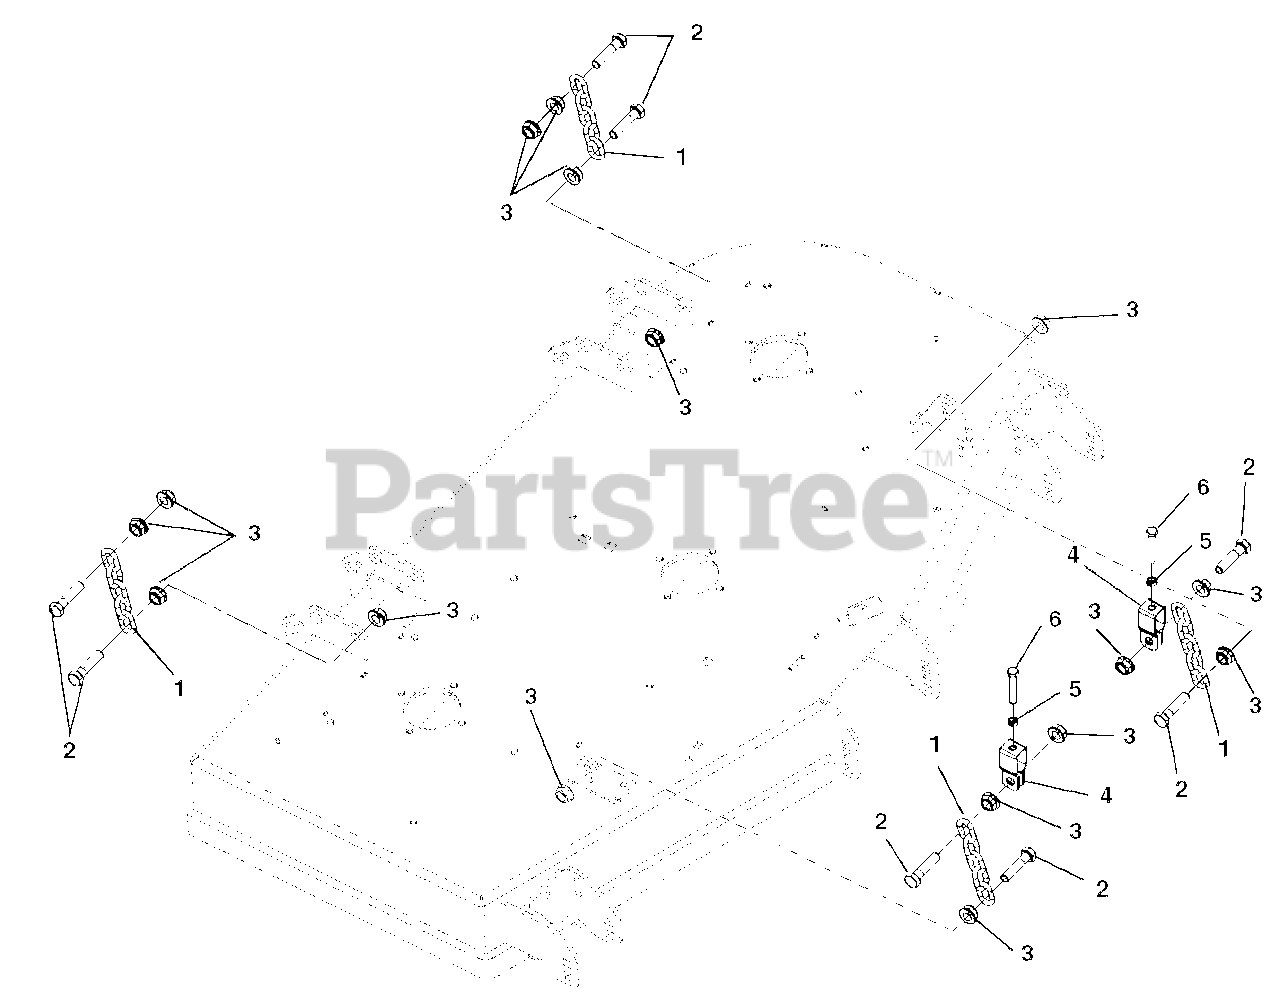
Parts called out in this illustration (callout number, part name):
1	Chain, Link
2	Bolt, Hex M12-1.75 x 50 Class 8.8
3	Nut, Spin Lock-Flange M12-1.75
4	Bracket, Deck Leveling
5	Nut, Jam .312-18
6	Bolt, Hex .312-18 x 2.00 FTH Grade 5
